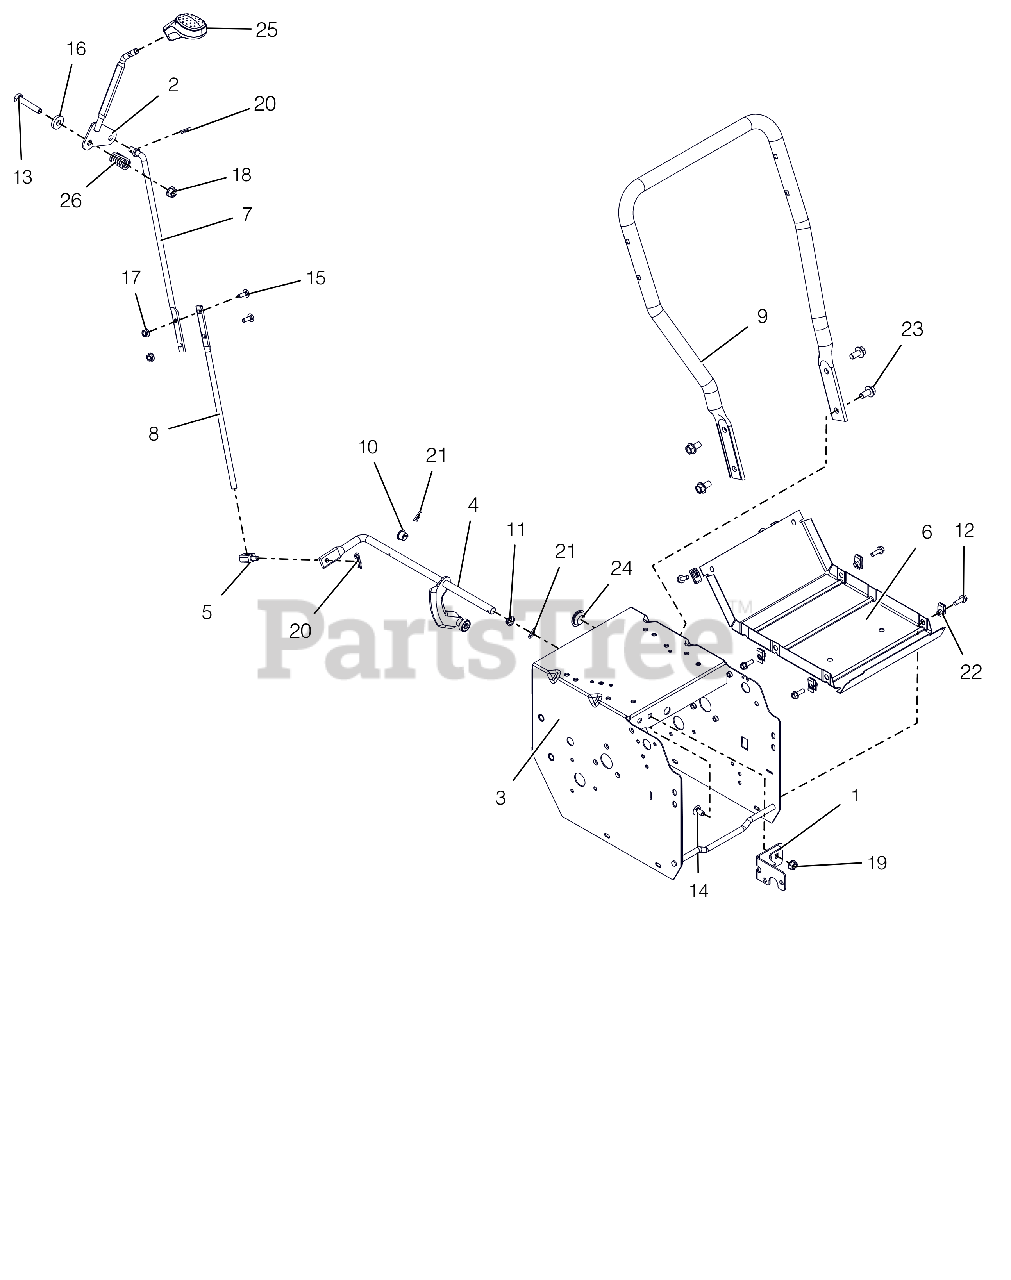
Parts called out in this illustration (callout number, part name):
1	WELDMENT, FRAME BRACKET
2	LEVER, CONTROL-SHIFT(WELDMENT)
3	WELDMENT, FRAME - DELUXE 16"
4	ARM, SHIFT-SMALL DASH (ASSY)
5	PIVOT,SHIFT ROD .375-16(TRUNN)
6	COVER, BOTTOM
7	ROD, SHIFT - UPPER
8	ROD, SHIFT - LOWER(SMALL DASH)
9	HANDLEBAR, LOWER - SM DELUXE
10	BUSHING, POLYLINER-.50 SPLIT
11	BUSHING, POLYLINER-.50 SNAPIN
12	BLT-HEX .25-20X.75 HWH YZ GR5
13	@BLT-HEX .38-16X2.00 GR5 YWZC
14	@BLT-RHDSSQNK .31-18X.62 G5YZ
15	@BLT-RDHDSQNK .25-20X.75 G5YZ
16	WSHR-FL-STL .406X1.00X.188 YWZ
17	@NUT-LK-CTR-FLG .25-20 YWZC
18	@NUT-LK-TOP-FLG .38-16 YWZC
19	@NUT-LK-TOP-FLG .31-18 YWZC
20	PIN-HAIR INT .08X.18X1.18 YWZC
21	CLIP, SPRING
22	NUT-RTNR .25-20X.56
23	BLT-SERHFWH .38-16X.75 YWZC
24	PLUG, HOLE - .875" NYLON
25	KNOB, CONTROL, DASH
26	SG-COMP .125X.781X1.250
